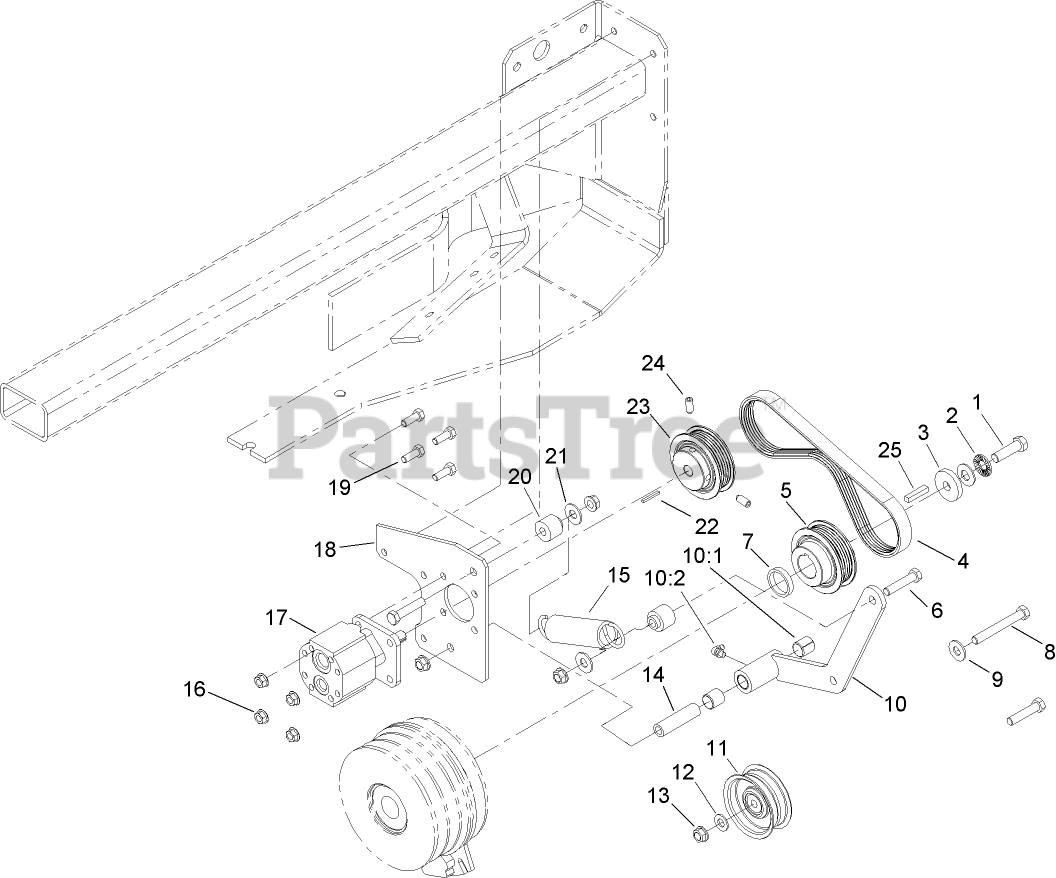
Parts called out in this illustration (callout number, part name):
1	SCREW-HH
2	WASHER-SPRING
3	WASHER-CLUTCH
4	BELT-POLY V
5	SHEAVE-5 RIB
6	SCREW-HH
7	SPACER-PUMP DRIVE, FAN
8	SCREW-HH
9	WASHER-FLAT
10	WHEEL PUMP TENSION ASM
10:1	SLEEVE-BEARING
10:2	FITTING-GREASE, 90 DEG
11	SHEAVE-IDLER
12	WASHER-FLAT
13	NUT-HHF, WHIZ
14	BUSHING-PIVOT, IDLER
15	SPRING-EXTENSION
16	NUT-HF
17	PUMP-FAN, HYD
18	PLATE-MATING, FAN PUMP
19	SCREW-HH
20	SPACER-SPRING, FAN PUMP
21	WASHER-FLAT
22	KEY-SQUARE
23	SHEAVE-5 RIB
24	SCREW-SET, HSH
25	KEY-SQUARE
